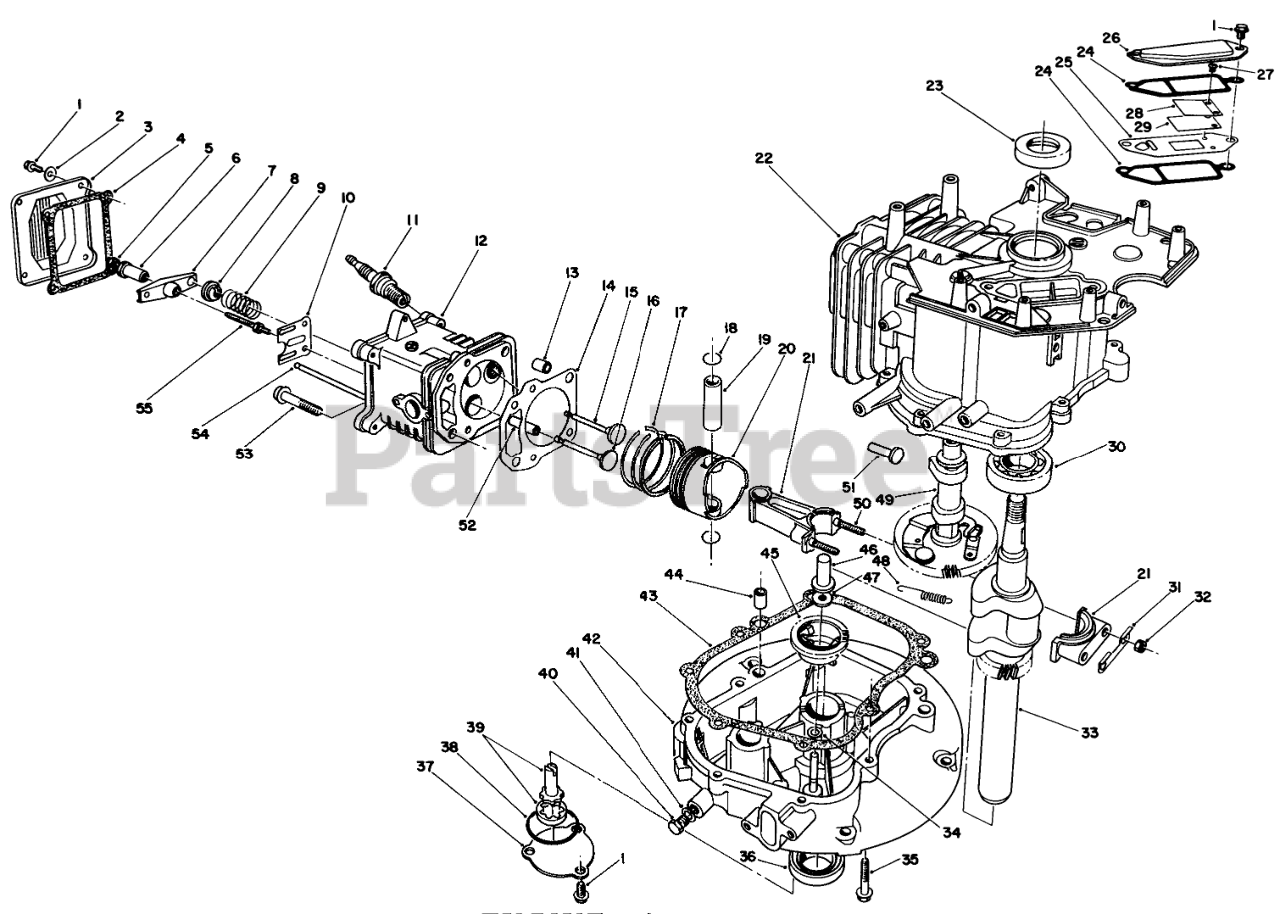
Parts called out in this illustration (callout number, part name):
2	WASHER
3	COVER
4	GASKET
6	PIVOT
8	RETAINER
9	SPRING
10	GUIDE
11	SPARK PLUG
12	Head-Cylinder (Incl. Ref. #52)
14	GASKET
15	VALVE-INTAKE
16	VALVE-EXHAUST
17	RING SET
18	CIRCLIP
20	PISTON
21	Connection Rod Assembly (Incl. Ref. #31, 32 & 50)
22	Block-Engine (Incl. Ref. #23, & 30)
24	GASKET
25	Plate-Breather
26	COVER
27	Screw-Reed Valve
28	Retainer-Reed Valve
29	Valve-Reed
30	BEARING
31	Plate-Lock
33	CRANKSHAFT
34	WASHER
37	COVER
38	O-RING
39	OIL PUMP
40	Plug-Oil Drain
41	GASKET
42	Crankcase
43	GASKET
45	GOVERNOR FLYWEIGHT ASM
46	PLUNGER
47	WASHER
48	SPRING
49	Camshaft Assy. (Incl. Ref. #48)
51	TAPPET
52	GUIDE
